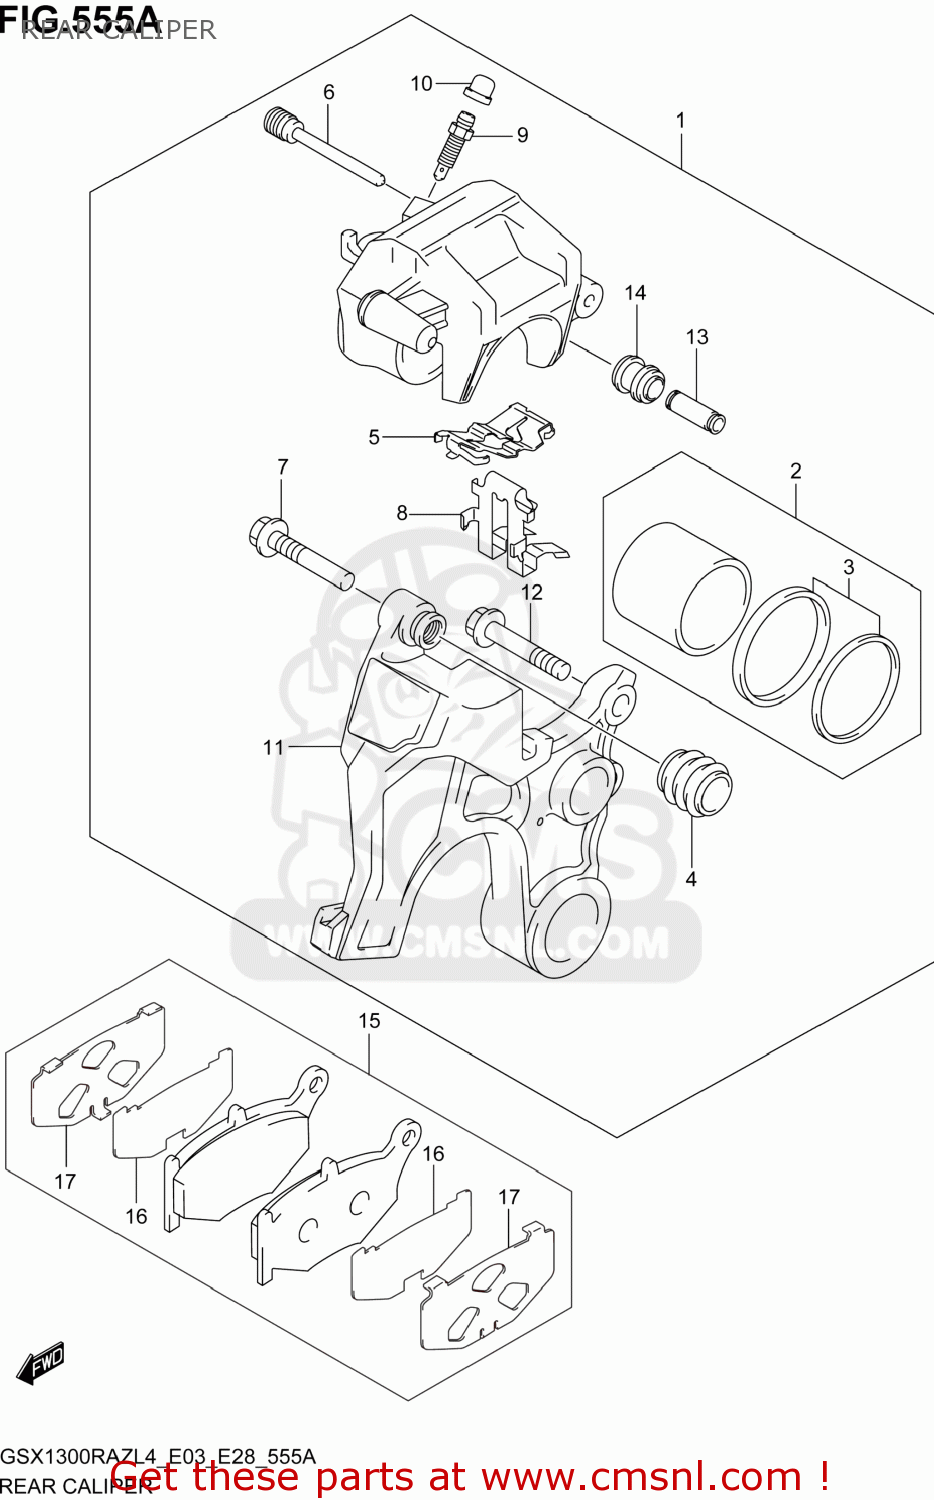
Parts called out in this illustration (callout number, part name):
1	CALIPER ASSY,REAR
2	PISTON SET
3	SEAL SET,PISTON
4	BOOT,AXLE
5	SPRING,PAD
6	PIN,PAD
7	PIN,BOLT
8	RETAINER
9	BLEEDER
10	CAP,BLEEDER PLUG
11	BRACKET
12	BOLT
13	SLEEVE
14	BOOT,SLEEVE
15	PAD & SHIM SET (NAS)
16	INSULATOR
17	SHIM
